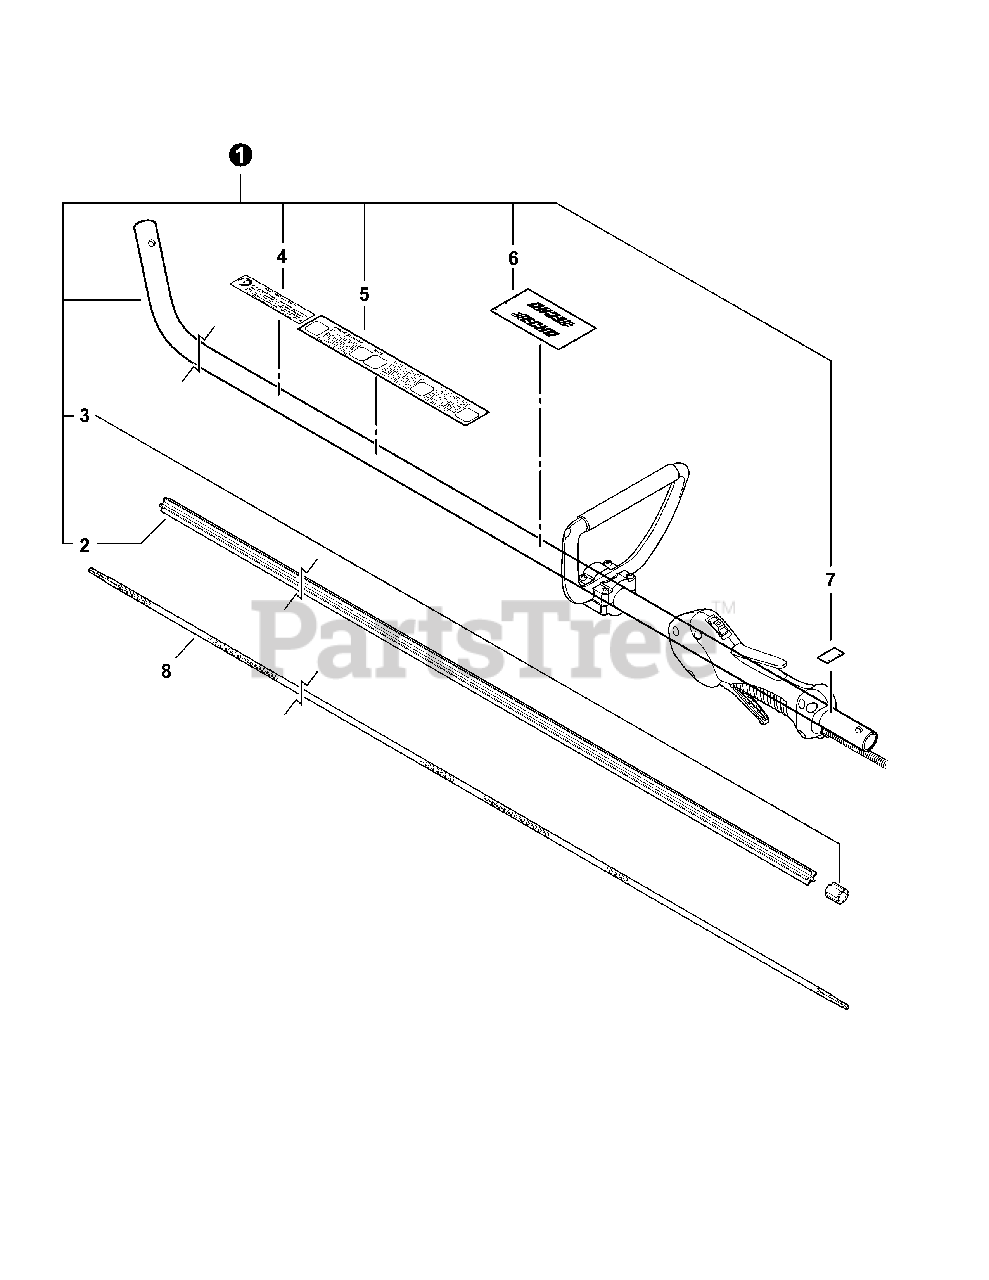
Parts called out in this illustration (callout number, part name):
1	MAIN PIPE ASSY
2	LINER, FLEXIBLE 21.6×1420
4	LABEL, CAUTION
5	LABEL, CAUTION
6	LABEL, HANDLE LOCATION
7	LABEL - ALIGNMENT
8	DRIVESHAFT - FLEXIBLE
